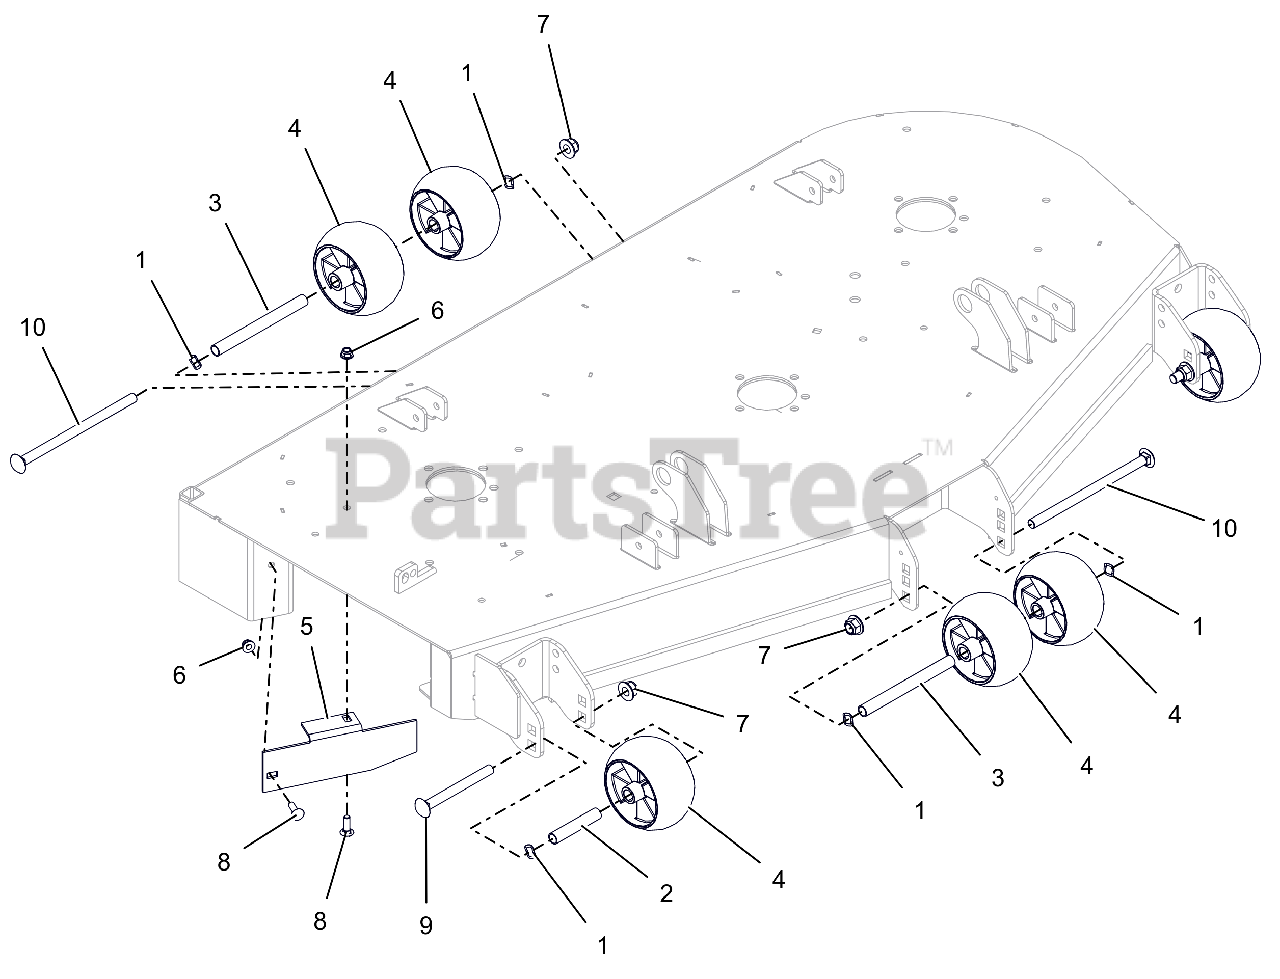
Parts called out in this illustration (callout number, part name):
1	WAVE WASHER .531X.781X.125FH
2	SPACER, .510X.625X3.35
3	SPACER, .510X.625X6.50
4	ANTI-SCALP WHEEL - 5X3 CTR
5	BAFFLE, DISCHARGE, 52"
6	NUT,NYL-FLG .31-18 GF ZCC
7	NUT,NYL-FLG .50-13 GF ZCC
8	BLT,RHSN .31-18X1.00 G5 ZCC
9	BLT, RHSN .50-13X5.00 G5 ZCC
10	BLT, RHSN .50-13X8.50 G5 ZCC
